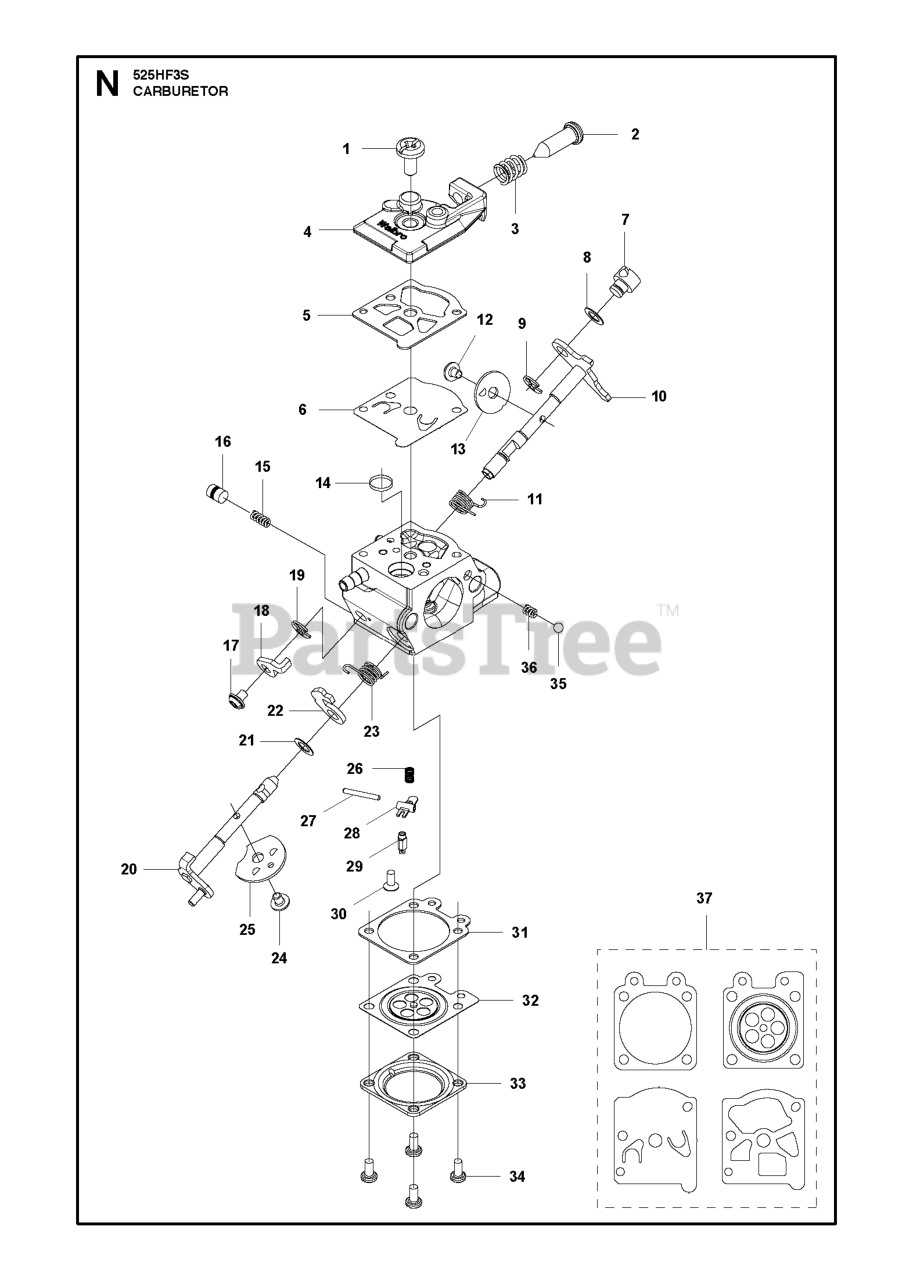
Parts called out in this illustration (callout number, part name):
2	RP BOLT 5/16-18 X3/4 ZN/YEL GR
5	RETAINER-SPRNG RB
6	BAR.SWAY.92.CRD
8	BOLT.3/8-24X1.25 GR8
9	LOCKWASHER
10	WASHER.BLADE
13	SHAFT ASM VENT
14	HOUSING.MANDREL.VENTED (MACHD)
17	BOLT.3/8-14X1.25
19	BOLT SHD 5/16-18
20	BOLT.3/8-24X1.25GR8. LHTHRD
21	LOCKNUT
26	SUPPORT
30	SCREW, WASHER HEAD
31	WASHER.SPACER.MANDREL
32	PULLEY MANDREL
33	NUT.FLANGE.LOCK.TOP
36	PULLEY.IDLER.4.25
41	NUT LOCK FLG 3/8-16 UNC
45	COVER.MANDREL.RH.CRD
46	SCREW.1/4-20X5/8
55	ARM.IDLER.92 CRD.2006
56	SPACER.RETAINER.MOWER
61	SPRING
68	BELT.DRIVE.92CM.CRD.2006
69	SHAFT.ASM.W/LWR.BRG.RH.THREAD
84	KEEPER, BELT IDLER
116	BOLT.SHOULDER.3/8-16X3-5/8.
117	RP WHEEL. GUAGE RALLY
119	WASHER
124	BOLT.3/8-16X1.50
130	BOLT.CARR.SQNK.5/16-18UNC.X3/4
131	CHUTE BAGGER
254	SCREW 3/8-16X1
296	BOLT
297	NUT CENTERLOCK
